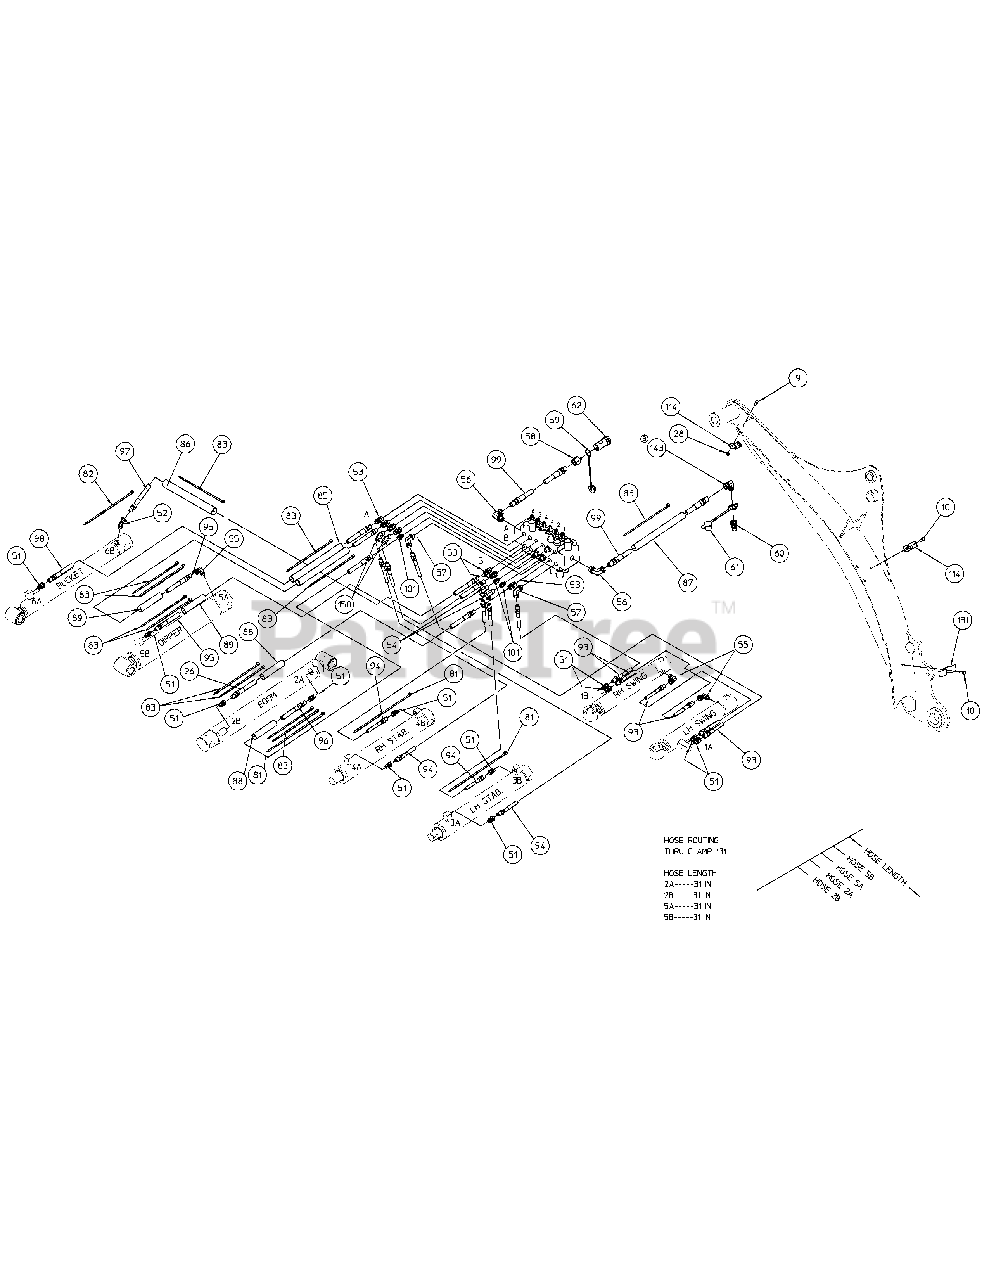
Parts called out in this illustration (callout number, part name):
1	Hydraulic Cylinder - Bucket
2	Hydraulic Cylinder - Swing
3	Hydraulic Cylinder - Boom
4	Hydraulic Cylinder - Dipper
5	Hydraulic Cylinder - Stabilizer
6	Bolt, Carriage 5/16 NC x 3/4"
7	Bolt, Carriage 5/16 NC x 1-1/4"
8	Bolt, 1/4 NC x 3/4"
9	Bolt, 5/16 NC x 3/4"
10	Bolt, 5/16 NC x 3/4" Thread Forming
11	Bolt, 5/16 NF x 3/4"
12	Bolt, 5/16 NF x 7/8"
13	Bolt, 5/16 NF x 1" Gr. 5
14	Bolt, 5/16 NF x 1.125" Gr. 5
15	Bolt, 5/16 NF x 2-1/4" Gr. 5
16	Bolt, 5/16 NF x 2.75" Gr. 8 SAE
17	Bolt, 5/16 NF x 4" Gr. 8
18	Bolt, 3/8 NF x 3/4"
19	Bolt, 3/8 NF x 1"
20	Bolt, 3/8 NF x 1-1/4"
21	Bolt, 3/8 NF x 2.5"
22	Bolt, 3/8 NF x 2-3/4"
23	Bolt, 3/8 NC x 5-1/2" Long Gr. 5
24	Bolt, 1/2 NF x 1"
25	Bolt, 1/2 NF x 3.25"
26	Nut, 1/4 NC
27	Nut, 5/16 NC
28	Locknut, 5/16 NC
29	Nut, 5/16 NF
30	Locknut, 5/16 NF
31	Locknut, 3/8 NC
32	Nut, 3/8 NF
33	Locknut, 3/8 NF
34	Locknut, 1/2 NF
35	Lockwasher, 1/4
36	Lockwasher, 5/16
37	Lockwasher, 3/8
38	Lockwasher, 3/8
39	Flat Washer, 5/16 STD
40	Washer, 5/16 SAE
41	Flat Washer, 3/8 SAE
42	Flat Washer, 1/2" Hardened
43	Machine Bushing, 1-1/2" OD x 1" ID x 18Ga.
44	Machine Bushing, 1-7/8" OD x 1-1/4" ID x 18Ga.
45	Machine Bushing, 2-1/2" OD x 1-3/4" ID x 18 Ga.
46	Cotter Pin, 3/32" Dia x 3/4"
47	Cotter Pin, 3/16" Dia x 1-1/2"
48	Cotter Pin, 1/4" Dia x 1-1/2"
49	Hair Pin Cotter, 3/64" Dia x 11/16"
51	Adapter Union, 9/16-18M x 3/8NPTF
52	Adapter Union, 9/16-18M x 3/8NPSM
53	Adapter Union, 3/4-16M x 3/8NPTF x Straight
54	Adapter Union, 3/8NPTM x 3/8NPTF x 90 degree
55	Adapter Union, 9/16-18M x 3/8NPTF x 90 degree
56	Adapter Union, 7/8-14M x 1/2NPSM x 90 degree
57	Adapter Union, 3/4-16M x 3/8NPTF x 90 degree
58	Adapter Pipe, 3/4-16NFM x 1/2NPTF
60	Coupler Nose, 3/4-16F Thread
62	Coupler Body
63	Garlock Bearing
64	Bronze Bearing
65	Garlock Bearing, 028DxR016
66	Stabilizer Pad
67	Cast Guide Link
68	Bucket Link
69	Clevis Pin, 3/16" Dia x 5/8"
70	Clevis Pin, 1/4" Dia x 7/8"
71	Pin Retainer
72	Swing Lock Pin
74	SMV Socket
75	SMV Bracket
77	Ball Joint - Shouldered
78	Ball Joint
79	Control Knob
80	Rubber Cap
81	Plastic Tie T150L
82	Plastic Tie T120L
83	Plastic Tie T50L
85	Hose Sleeve FC45-16 x 30" Long
86	Hose Sleeve FC425-16 x 19" Long
87	Hose Sleeve FC425-16 x 48" Long
88	Hose Sleeve FC425-16 x 63" Long
89	Hose Sleeve FC425-16 x 79" Long
90	Hydraulic Fluid
91	Grease Fitting
92	Grease Fitting (Two are part of #000187 Cyl.)
93	Hydraulic Hose, 3/8NPTM x 3/8NPTM x 20" long
94	Hydraulic Hose, 3/8NPTM x 3/8NPTM x 36" long
95	Hydraulic Hose, 3/8NPTM x 3/8NPTM x 80" long
96	Hydraulic Hose, 3/8NPTM x 3/8NPTM x 60" long
97	Hydraulic Hose, 3/8NPTM x 3/8NPTM x 105" long
98	Hydraulic Hose, 3/8NPTM x 3/8NPTM x 125" long
99	Hydraulic Hose, 1/2NPTM x 1/2NPTM x 54" long
100	Control Valve
101	Adapter Union, 7/16-20M x 3/8NPTF
102	Rear Shroud
103	Stabilizer Lever Control Rods
104	Control Rod
105	Buck Link Pin
106	Pivot Pin, Boom Cyl. Rod 1-1/4" Dia. x 6" Long
107	Thrust Washer
108	Stab Pivot Shaft
109	Stabilizer Cylinder Pin
110	SMV Socket Mount
111	Stabilizer Pivot Pin
112	Stabilizer Control Lever
113	Lever Bracket
114	Hose Clamp - Short
115	Upper Pivot Pin Weldment
116	Lower Pivot Pin Weldment
117	Retaning Collar
122	Swing Cylinder Pin Weldment
123	RH Pivot Weldment
124	LH Pivot Weldment
126	Pivot Pin Weldment, Boom 1-3/4" Dia. x 2-3/4" Lg
127	Swing Cylinder Pin Weldment
128	RH Toe Shield
129	LH Toe Shield
130	Cylinder Base Pin
131	Hose Clamp - Long
132	Seat Plate Weldment
133	Mainframe Weldment
134	Dipper Weldment
135	Boom Weldment
136	Swing Frame Weldment
137	Stabilizer Weldment
138	Grab Bar Weldment
139	Valve Mount Weldment
140	Front Shroud Weldment with Decals
141	RH Joystick Weldment
142	LH Joystick Weldment
144	Rubber Street Pad
145	Bolt, Hex 1/4-20 x 1.750 Gr 5
146	Bolt, Hex 1/4-20 x 2.0
147	Nut, hex 1/4-20 Gr 5 Lock
148	Flat Washer, 1/4 Hardened
149	Step Weldment
150	Adapter Union, 45 degree
